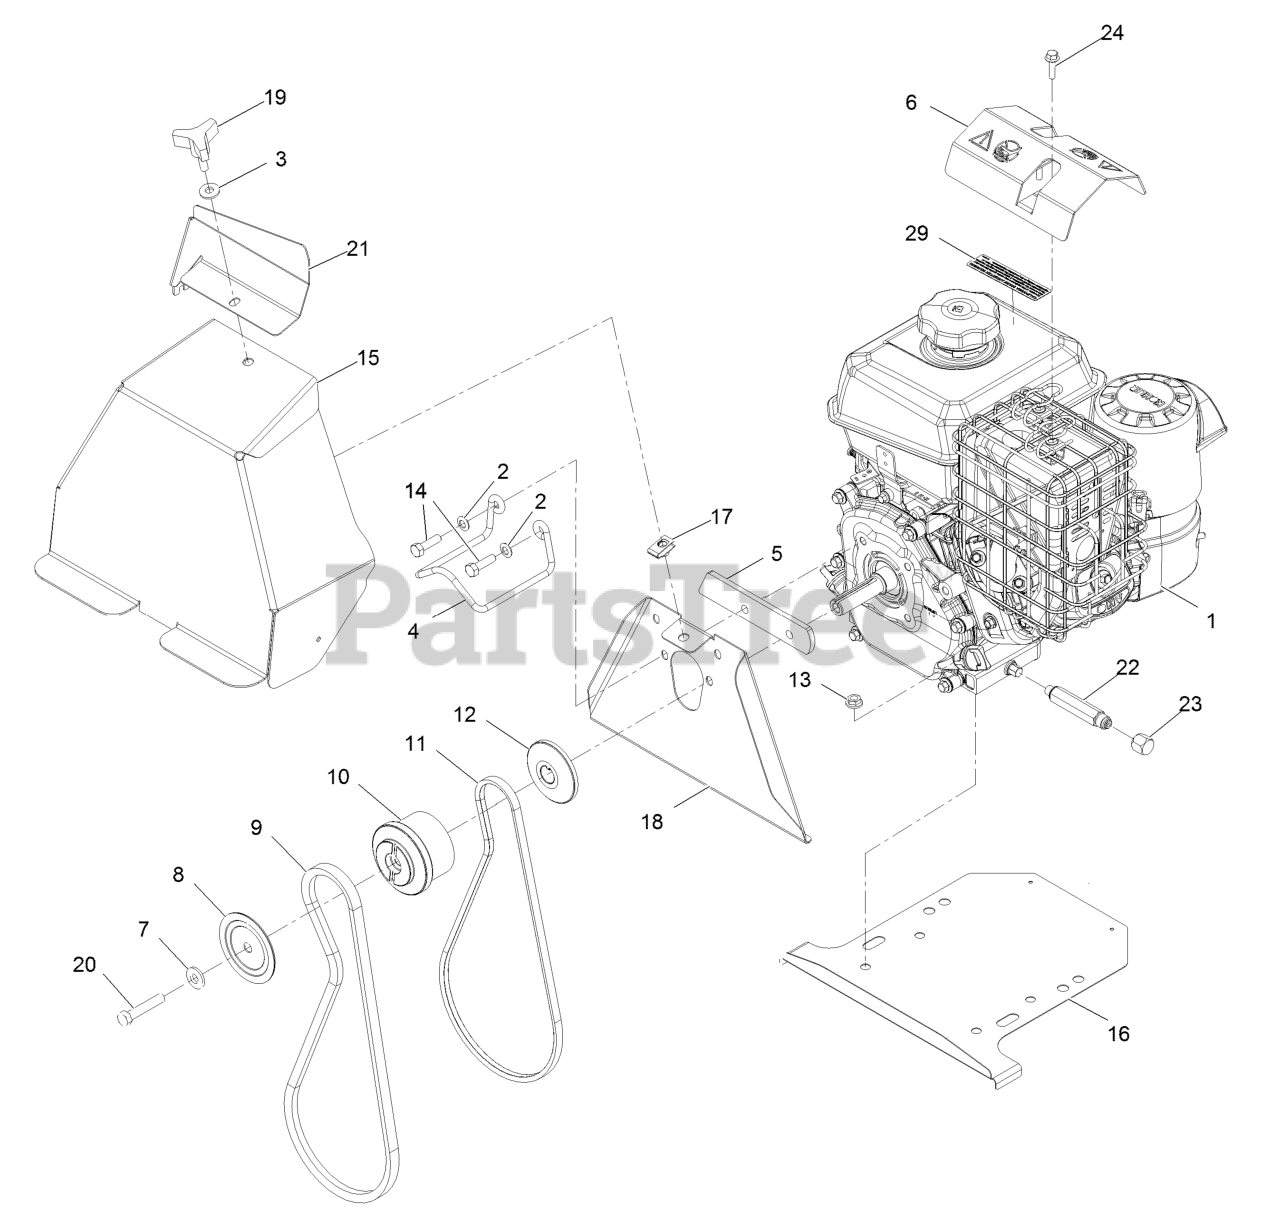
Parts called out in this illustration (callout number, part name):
2	WASHER-BELLEVILLE
3	WASHER-SPRING
5	SPACER-COVER, BELT
6	DEFLECTOR-DEBRIS, MUFFLER
7	WASHER-BELLEVILLE
8	SHEAVE-HALF, IMPELLER
9	BELT-BLOWER
10	PULLEY-ENGINE, CENTER
11	V BELT-TRACTION
12	SHEAVE-HALF, TRACTION
14	SCREW-HH
15	COVER - BELT
16	SHIELD-DRIVE
18	COVER-BELT, BACK
20	SCREW-HH
21	SHIELD-ICE, KC CH270
22	ADAPTER
24	SCREW-HHF
29	DECAL-ARRESTER, SPARK
